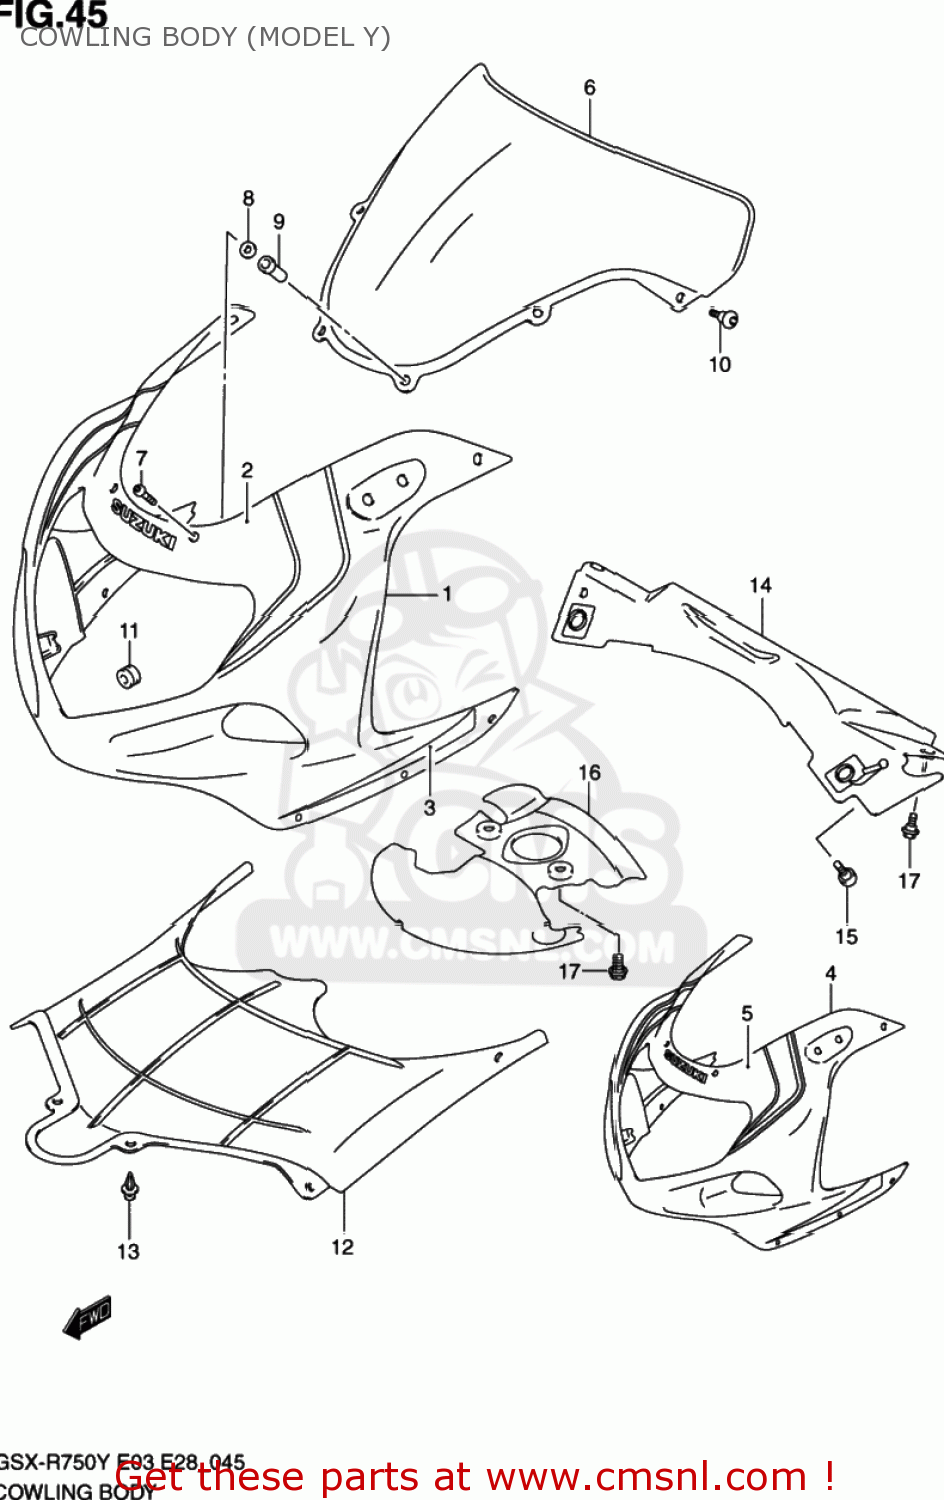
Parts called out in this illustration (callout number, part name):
1	COWLING COMP,BODY
2	TAPE,COWL BODY FR
3	TAPE SET,COWL BODY SIDE
4	COWLING COMP,BODY
5	TAPE,COWL BODY FR
6	WINDSCREEN
7	SCREW(5X14)
8	WASHER
9	NUT
10	SCREW(5X16)
11	CUSHION
12	COVER,BODY COWLING
13	CLIP(BLACK)
14	COVER,COWLING FR LWR
15	SCREW(5X16)
16	COVER,LWR BRACKET
17	BOLT
